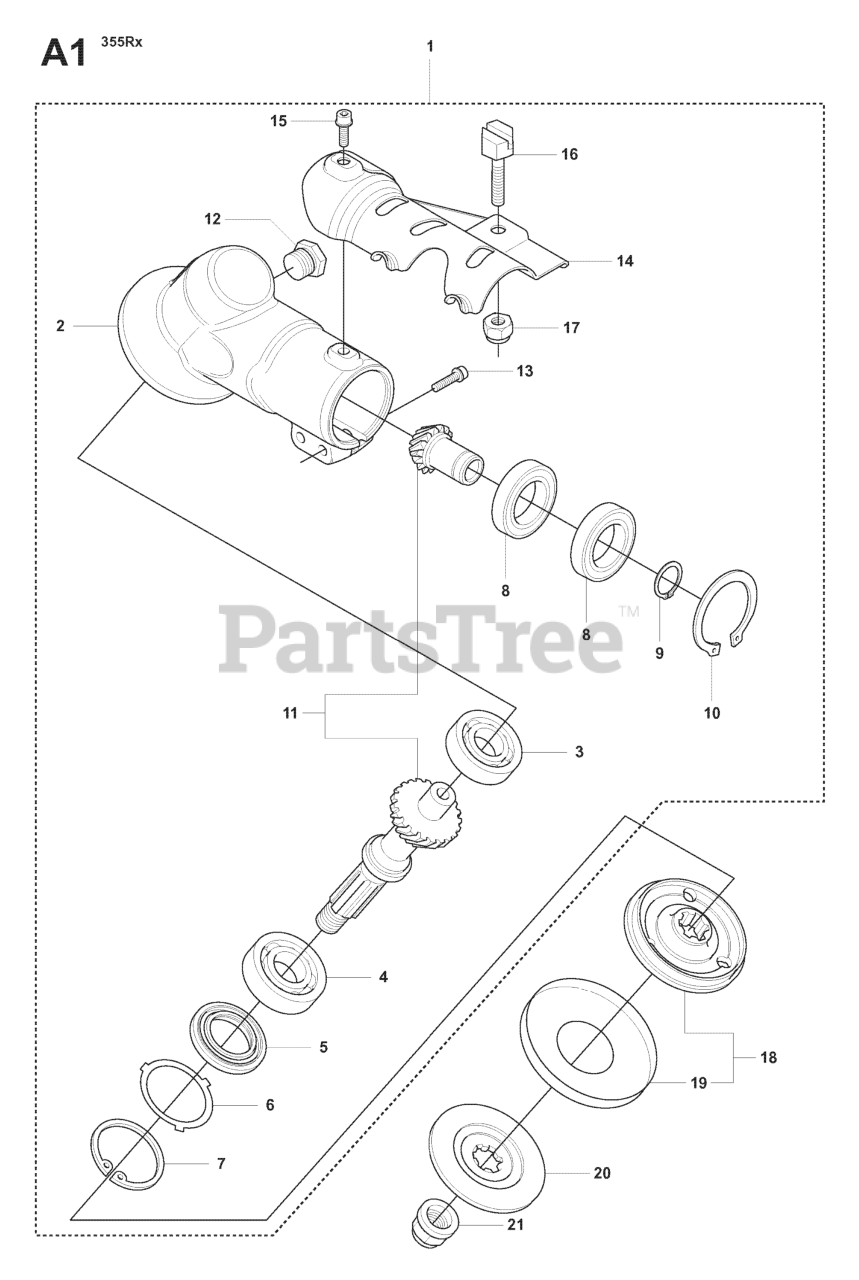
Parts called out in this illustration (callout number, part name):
1	BEVEL GEAR
2	GEAR HOUSING
3	BALL BEARING
4	BALL BEARING
7	RETAINING RING SGH 35
8	BALL BEARING
9	RETAINING RING SGA 15
10	RETAINING RING
11	BEVEL GEAR
14	ATTACHMENT PLATE
17	LOCKNUT M6
18	RP CARRIER
19	GRASS SEALING
20	SUPPORT FLANGE
21	BLADE NUT
